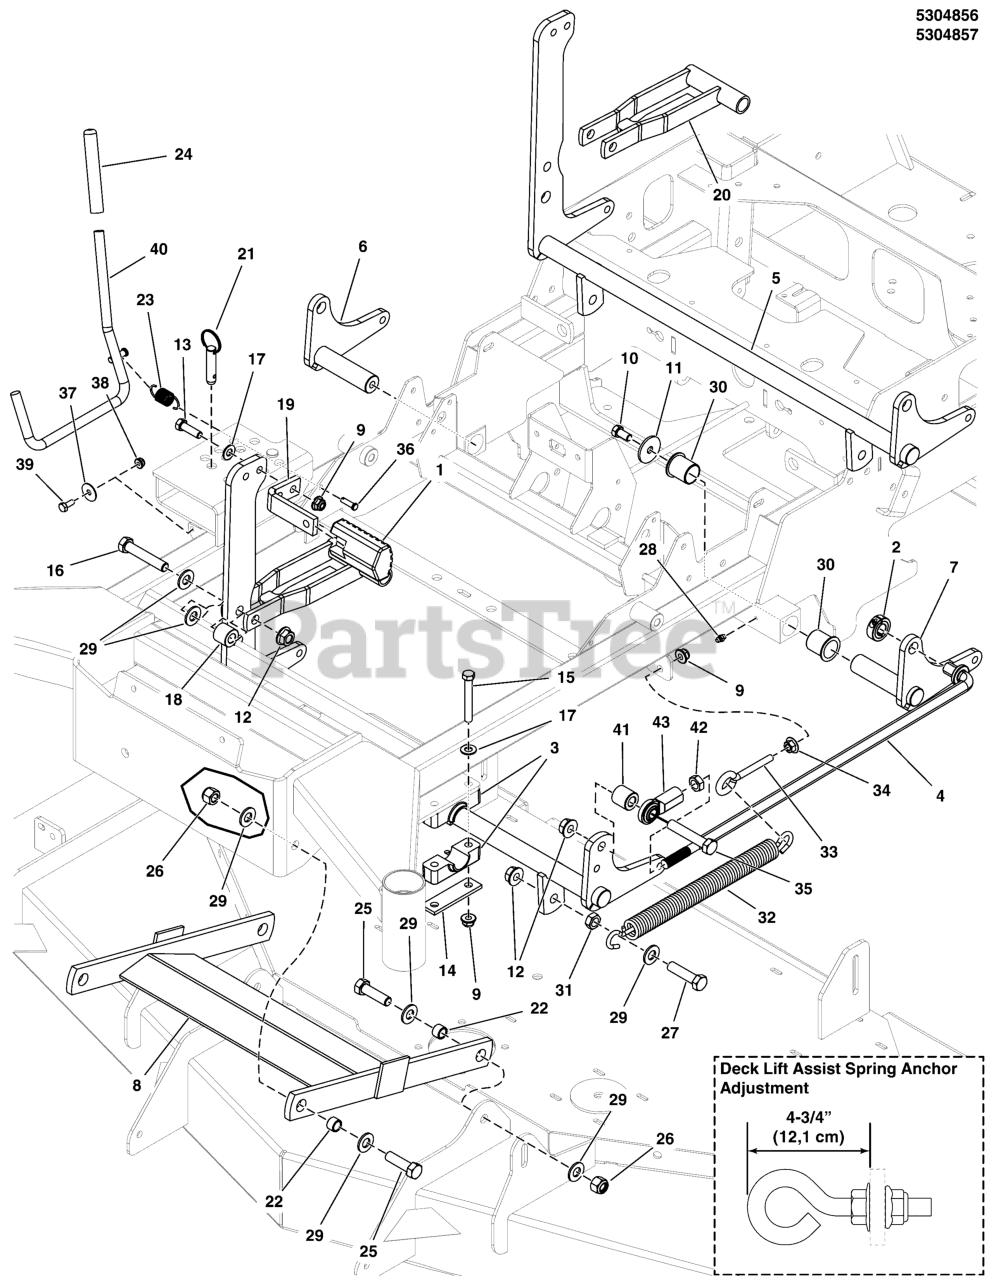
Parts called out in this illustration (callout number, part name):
1	PEDAL, Rubber
2	COLLAR, 5/8 SPLIT
3	PIVOT BLOCK, PLASTIC
4	ROD, DECK LIFT, 125XT
5	WELD, DECK LIFT SHAFT, 125 - BLK
6	WELD, DECK LIFT PIVOT, RH - BLK
7	WELD, DECK LIFT PIVOT, LH - BLK
8	WELD, PULLER BAR, 125 FRAME - BLK
9	NUT, 3/8-16 HEX NYLOCK FLANGE
10	BOLT, 3/8-16 X 3/4, PLT W/PATCH
11	WASHER, .390 X 1.50 X .109, CZ
12	NUT, Hex Flange, Nylock, 1/2-13
13	BOLT, 3/8-16 X 1-1/4" GD5 CZ
14	PLATE, PIVOT BLOCK SUPPORT - BLK
15	BOLT, 3/8-16 X 2-3/4" GD5 CZ
16	BOLT, 1/2-13 X 2-3/4 GD5 CZ
17	WASHER, 3/8 SAE
18	SPACER, .52 X 1.00 X .88, PM, CZ
19	PEDAL, FOOT - BLK
21	PIN, HITCH, 1/2 X 2.00 OAL, CZ
22	INSERT, BEARING
23	SPRING-EXT, .740 ODX2.025LGX.072WR, BLK
24	GRIP, FOAM, .475 X 4.35 X .095
25	BOLT, 1/2-20 X 1-3/4" GD8 CZ
26	NUT, Hex, Nylon Lock, 1/2-20
27	BOLT, 1/2-13 X 2" GD5 CZ
28	GREASE FITTING, 1/4-28 STRAIGHT
29	WASHER, 1/2 SAE
30	BUSHING, 1.00 X 1.13 X 1.38, PLASTIC
31	NUT, 1/2-13 HEX JAM
32	SPRING-EXT, 1.00 ODX13.25LGX.177WR, BLK
33	EYE BOLT, 3/8-16 X 6, 3THRD, 1EYE, CZ
34	NUT, 3/8-16 HEX SERRATED FLANGE
35	BOLT, 1/2-13 X 1-3/4 GD5 CZ
36	PIN, CLEVIS, 1/4 X 1/2, PLATED
37	WASHER, 1/4 FENDER
38	NUT, 1/4-20 HEX NYLOCK FLANGE
39	HHCS, 1/4-20 X 0.625, GR5, ZINC/CLEAR
40	WELD, Rod, Deck Lift - BLK
41	SPACER, .52 X 1.00 X 1.00
42	NUT, 1/2-20 HEX JAM
43	JOINT-BALL .500-20 THD .500ID, CLR ZINC
